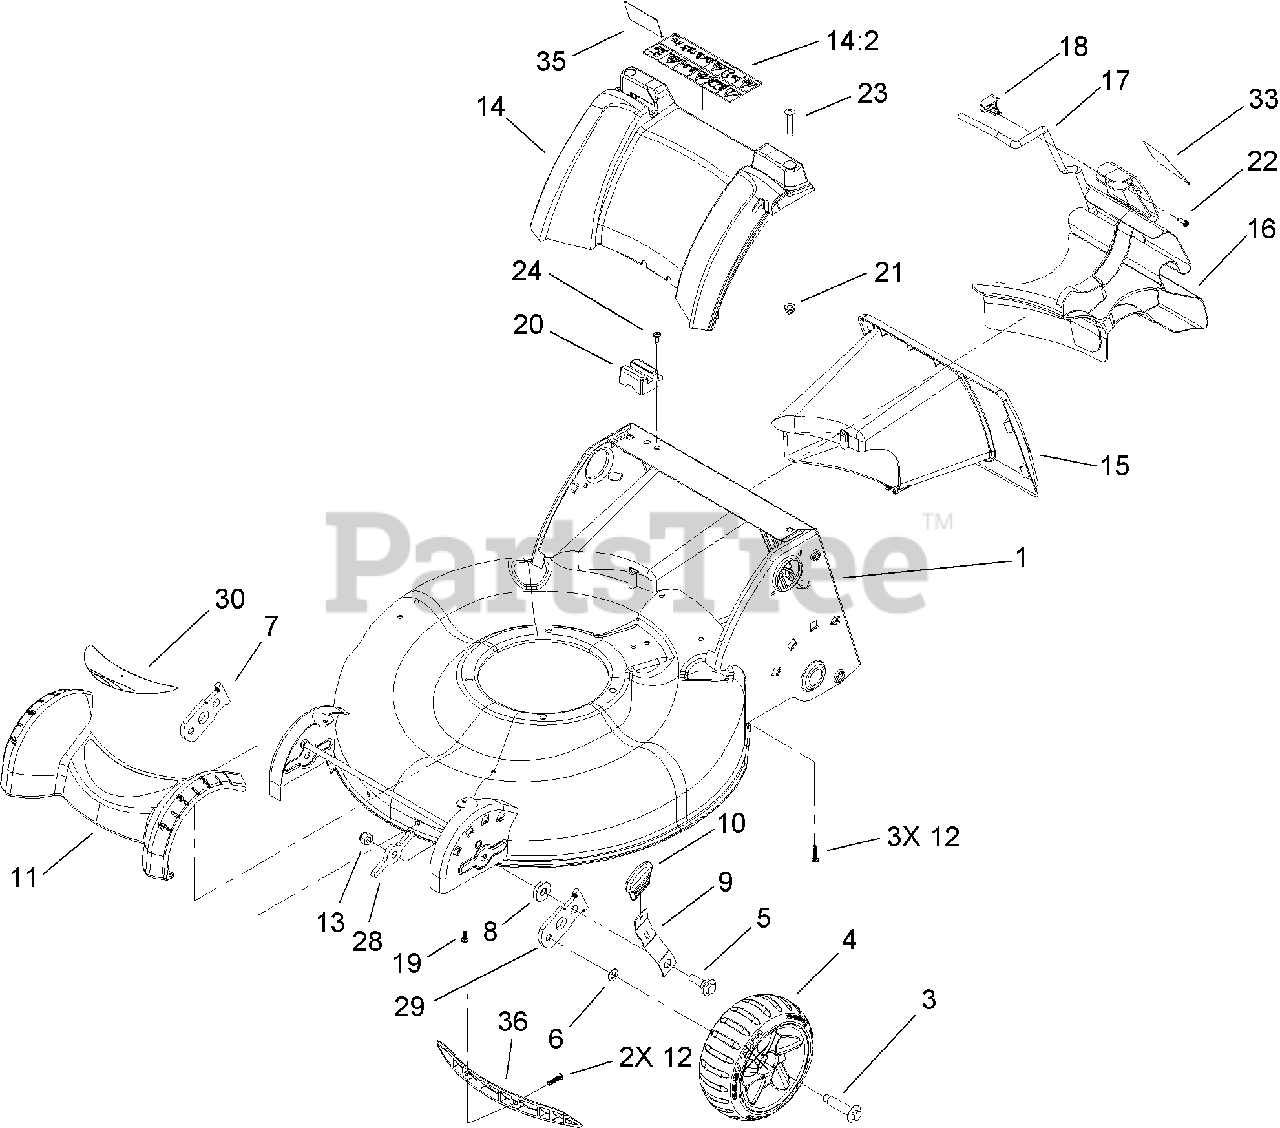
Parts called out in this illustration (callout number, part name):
1	HOUSING ASM
3	BOLT-SHOULDER
4	7 INCH FRONT WHEEL ASM
5	BOLT-SHOULDER
7	ARM-PIVOT, RH
9	ARM-SPRING
10	KNOB-LEVER, HOC
11	COVER-FRONT
12	SCREW-PLASTITE
13	NUT-LOCK, NI
14	COVER-REAR
14:2	DECAL-WARNING
16	PLUG-CHUTE
17	LATCH-PLUG
18	RETAINER-LATCH
19	SCREW-PLASTITE
20	MODULE-SWITCH
21	NUT-CLIP
22	SCREW-PPH
23	SCREW-PTH
24	SCREW-THREAD FORMING
28	WASHER-SUPPORT, FRONT
29	ARM-PIVOT, LH
33	DECAL-MULCH PLUG, CE
35	DECAL-BAG ATTACHMENT, CE
36	INSERT-HOUSING
